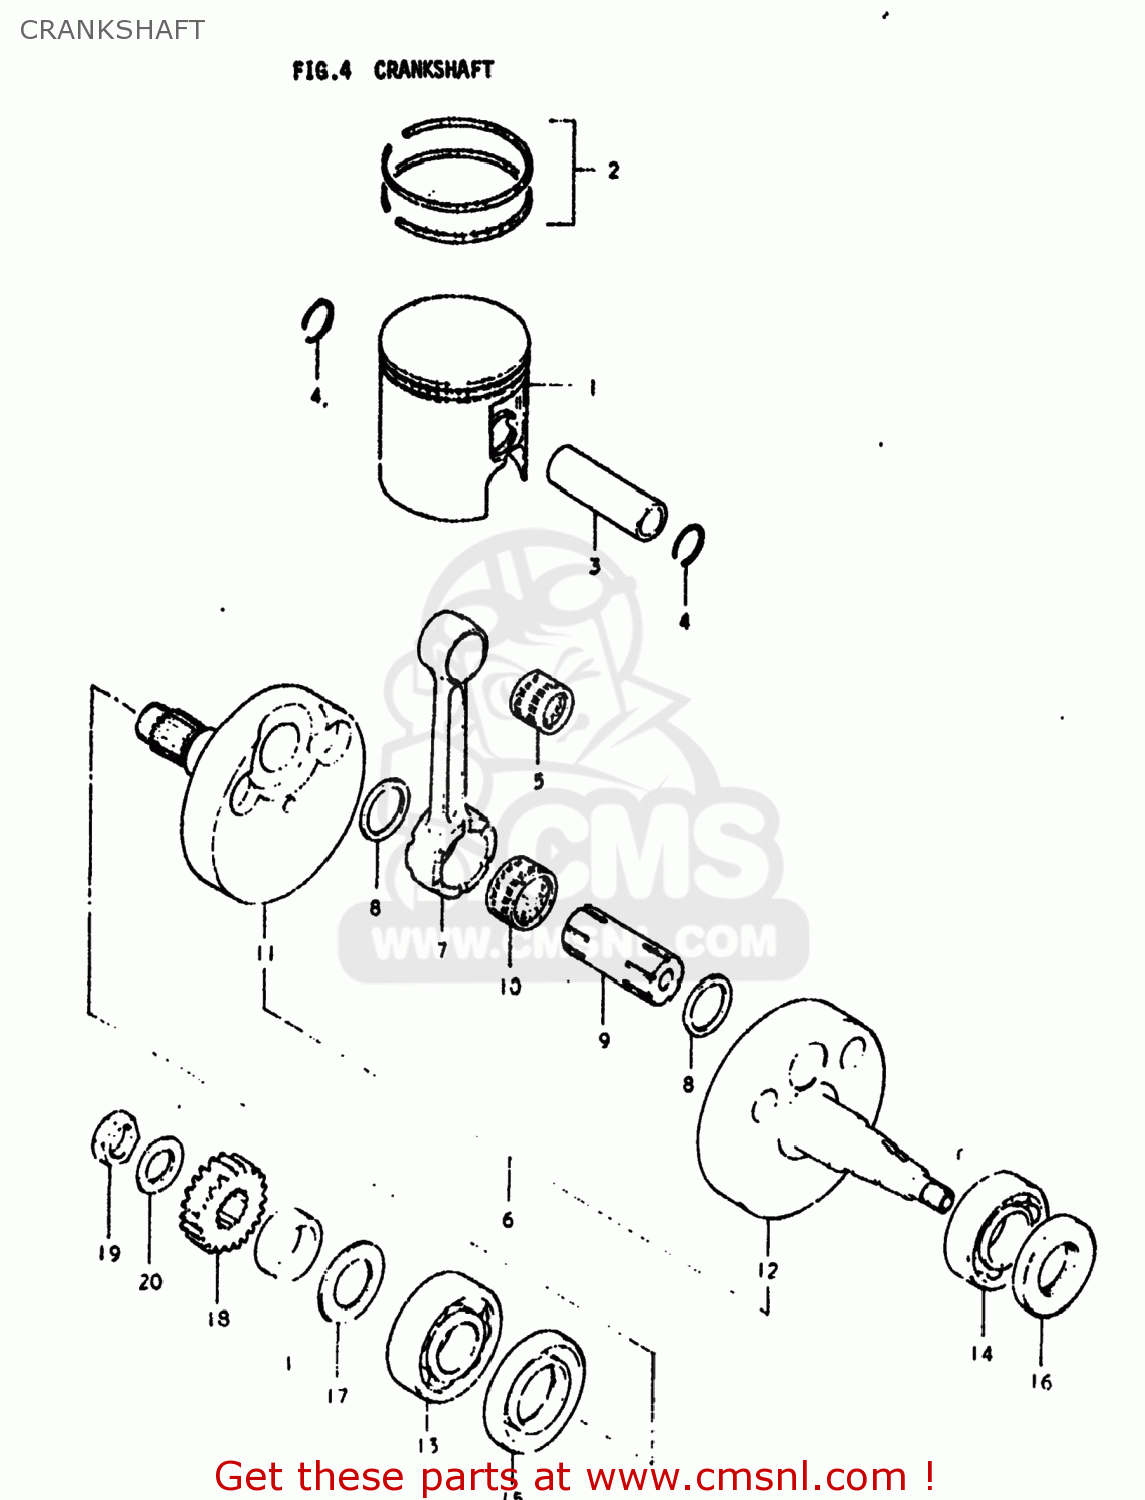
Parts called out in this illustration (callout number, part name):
1	PISTON
2	RING SET,PISTON
3	PIN,PISTON
4	RING,SNAP 16MM
5	BEARING
6	CRANKSHAFT ASSEMBLY
7	ROD,CONNECTING
8	WASHER(22X35X1)
9	PIN,CRANK
10	BEARING 22X28X16
11	CRANKSHAFT
12	CRANKSHAFT,LEFT
13	BEARING
14	BEARING
15	SEAL,OIL(30X56X9)
16	SEAL,OIL(25X44X7)
18	GEAR,PRIMARY DRIVE
19	NUT
20	WASHER
21	SPACER(22X32X11.5)
